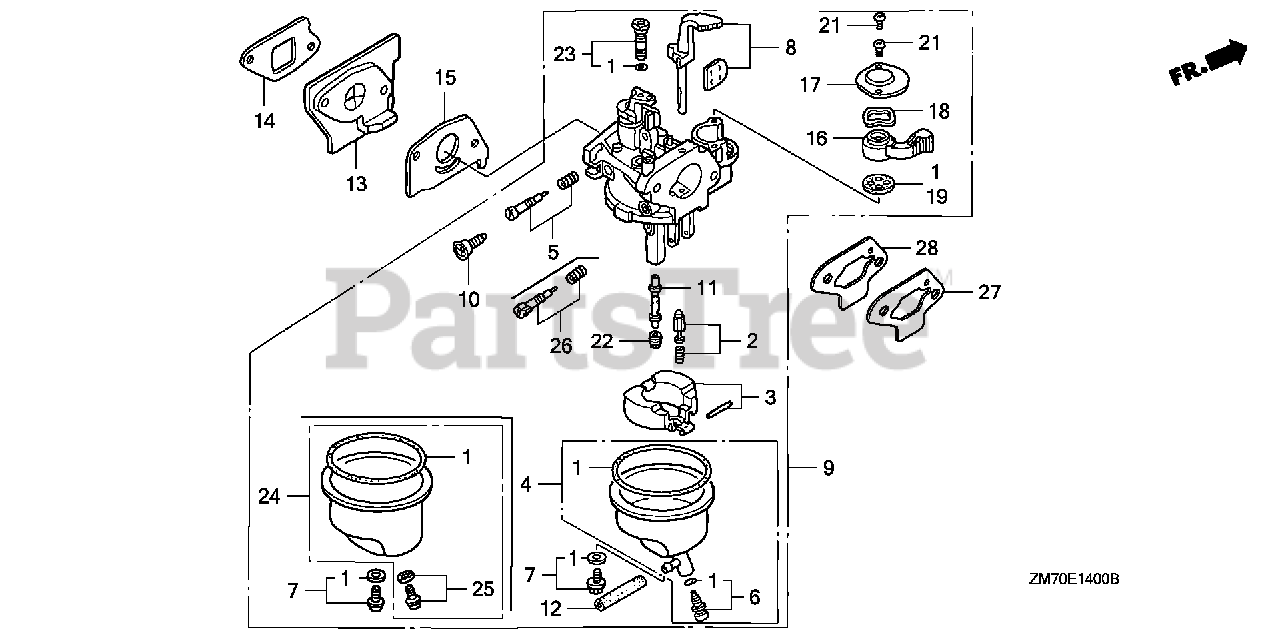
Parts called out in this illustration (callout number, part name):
1	GASKET SET
2	VALVE SET, FLOAT (SEAT NOT INCLUDED)
4	CHAMBER SET, FLOAT
6	SCREW SET, DRAIN
8	CHOKE SET (CARBURETOR NO.)
9	CARBURETOR ASSY. (BF32G A)
10	SCREW, THROTTLE STOP
11	NOZZLE, MAIN (CARBURETOR NO.)
12	BULK HOSE, VINYL (3.5X6.5X8000) (3.5X6.5X100)
13	INSULATOR, CARBURETOR
14	GASKET, INSULATOR
15	GASKET, CARBURETOR
16	LEVER, PETCOCK
17	PLATE, LEVER SETTING
18	SPRING, PETCOCK LEVER
19	GASKET, PETCOCK
21	SCREW, PAN (3X6)
22	JET, MAIN (#48) (CARBURETOR NO.)
22	JET, MAIN (#50)
22	JET, MAIN (#52) (CARBURETOR NO.)
23	JET SET, PILOT (#35)
26	SCREW SET, PILOT (CARBURETOR NO.)
27	SPACER, CARBURETOR
28	GASKET, AIR CLEANER
